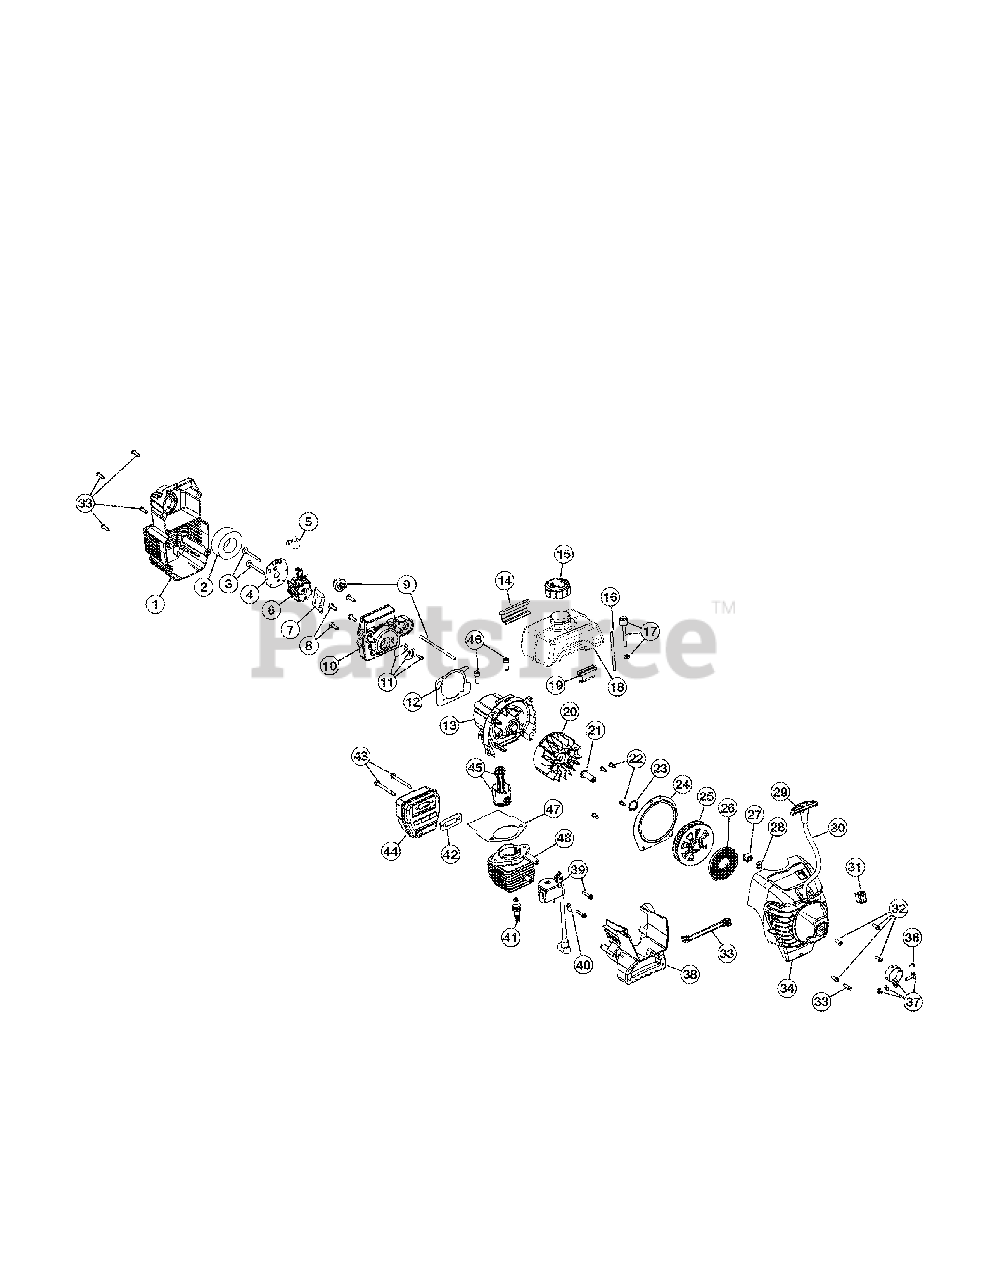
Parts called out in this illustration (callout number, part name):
1	Air Cleaner Cover Assembly (includes 2 & 33)
2	Air Cleaner Filter
3	Carburetor Mounting Screws
4	Choke Plate
5	Choke Lever
6	Carburetor Assembly (includes 7 & 17)
7	Carburetor Gasket
8	Carb Mount Screw
9	Primer and Hose Assembly
10	Carburetor Mount Assembly (includes 8, 11 & 12)
11	Reed Assembly
12	Carburetor Mount Gasket
13	Crankcase Service Assembly (includes 8)
14	Rear Mounting Pad
15	Fuel Cap Assembly
16	Fuel Return Line
17	Fuel Line Assembly
18	Fuel Tank Assembly (includes 15-17)
19	Front Mounting Pad
20	Flywheel Assembly
21	Square Nut Drive
22	Plate Screw
23	Palnut
24	Pressure Plate (includes 22 & 27)
25	Recoil Pulley Assembly (includes 23)
26	Recoil Spring
27	Eyelet Retainer
28	Rope Guide
29	Pull Handle
31	Switch Assembly
32	Housing Screw
33	Cover Screw
33	Wire Lead
34	Starter Housing Assembly (includes 22-34)
36	Anti-Rotation Screw
37	Clamp Assembly (includes 36)
38	Shroud Extension and Stand (includes 33)
39	Module Assembly
40	Ground Tab
41	Spark Plug
42	Exhaust Gasket
43	Muffler Mounting Bolt Assembly
44	Muffler Assembly (includes 42, 43 & spark arrestor)
45	Piston & Rod Assembly
46	Cylinder Bolt
47	Cylinder Gasket
48	Cylinder Assembly (includes 46 & 47)
